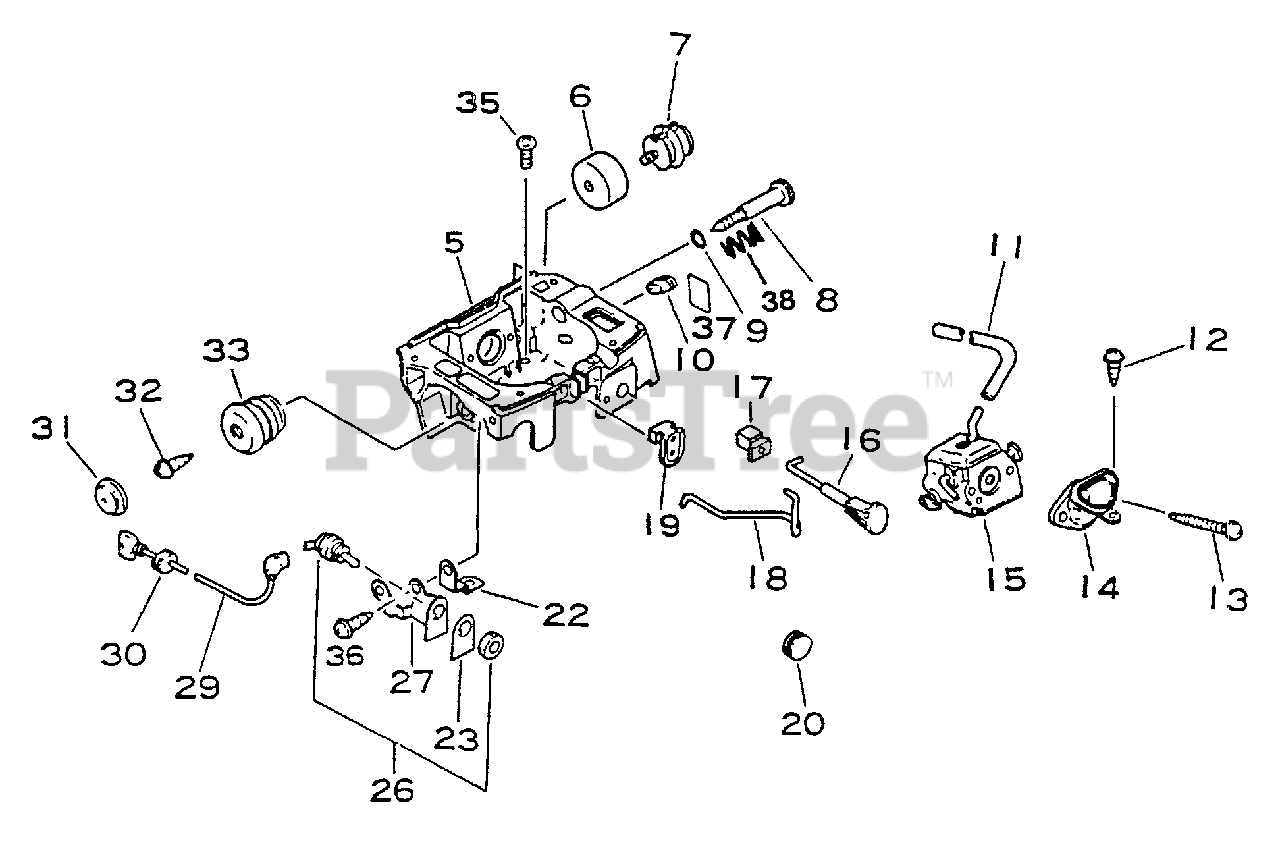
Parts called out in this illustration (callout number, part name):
5	CASE, CARBURETOR
6	PLATE, CUSHION
7	CUSHION
8	SCREW, IDLE ADJUST
9	O-RING - 6
11	PIPE - IMPULSE
12	SCREW - 5X14
13	SCREW - 5X55
14	GASKET
15	CARBURETOR
16	ROD, CHOKE
17	GROMMET
18	ROD, THROTTLE
19	GUIDE, THROTTLE ROD
22	TERMINAL - GROUND
23	LABEL - SWITCH
26	IGNITION SWITCH ASSY
27	BRACKET, SWITCH
29	LEAD - GROUND
31	CAP, CUSHION
33	CUSHION
35	SCREW - 5X20
36	SCREW - 5X10
37	LABEL - IDLE
38	SPRING, IDLE ADJUST
